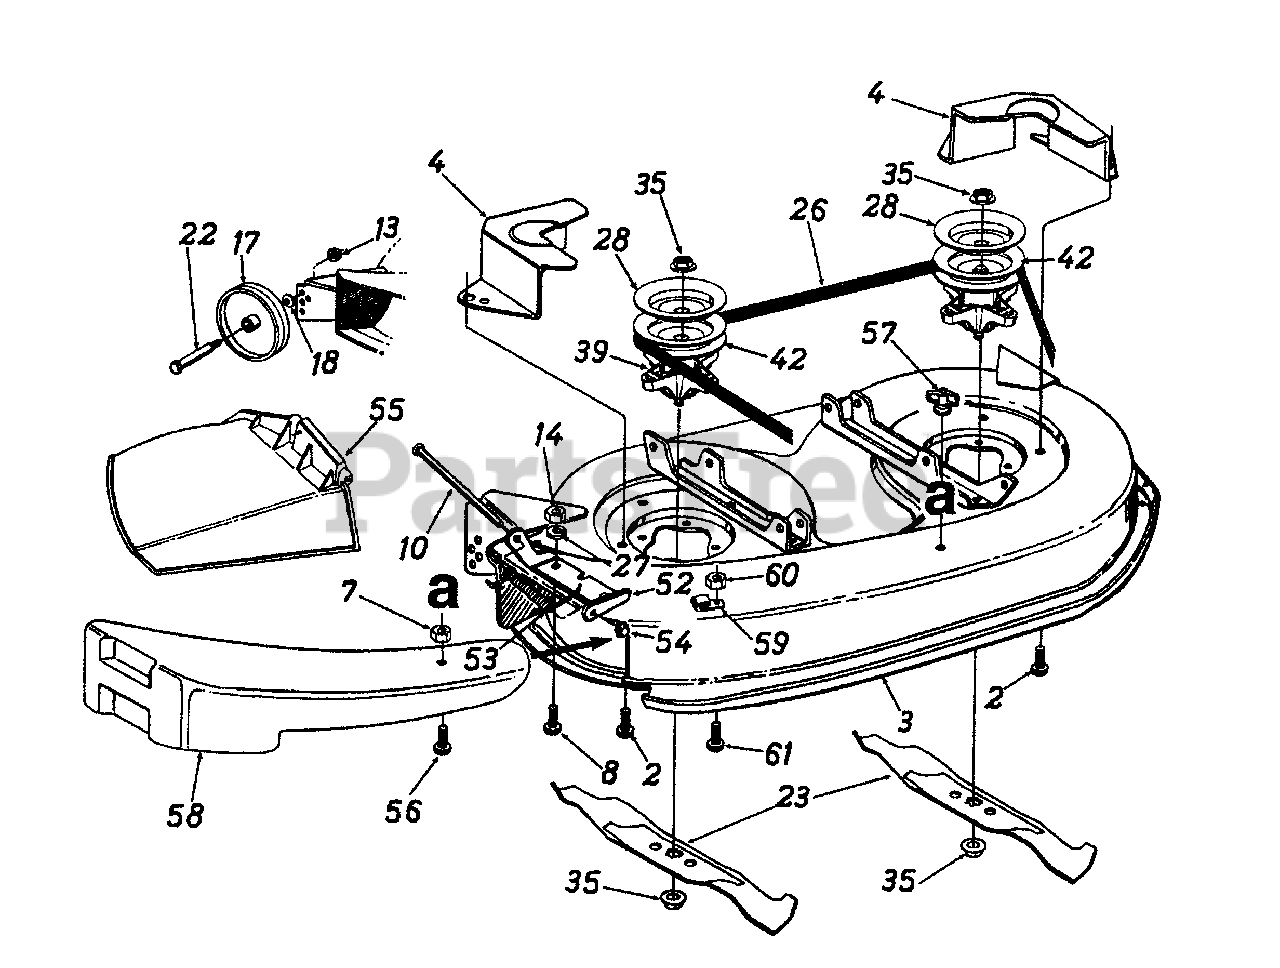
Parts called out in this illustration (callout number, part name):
2	Hex Wash. Hd. TT-Tap Scr. 5/16-18 x .75" Lg.
7	Hex L-Nut 1/4-20 Thd.
8	Hex Bolt 1/4-20 x .62"
10	Hinge Pin
13	Hex Top L-Nut 3/8-16 Thd.
14	Hex Nut 1/4-20 Thd. (Gr. 5)
17	Deck Wheel--5"
18	Bell-Wash. .40" I.D. x .88" O.D.
22	Shld. Bolt .498" Dia. x 1.53"
23	3 in 1 Blade
26	V-Belt
27	Bell-Wash. 1/4" I.D.
28	Brake Disc
35	Hex Flange Nut 5/8-18 Thd.
39	Blade Spindle Ass'y. Comp.
42	5.75" Dia. Pulley
52	Hinge Mtg. Brkt.
53	Torsion Spring
54	Push Nut
55	Chute Ass'y. Comp.
56	Hex Bolt 1/4-20 x 1" Lg.
57	Wing Nut 1/4-20 Thd.
58	Mulching Plug
59	Retainer Hook Brkt.
60	Hex Sems Nut 1/4-20 Thd.
61	Hex Bolt 1/4-20 x .62" Lg.
